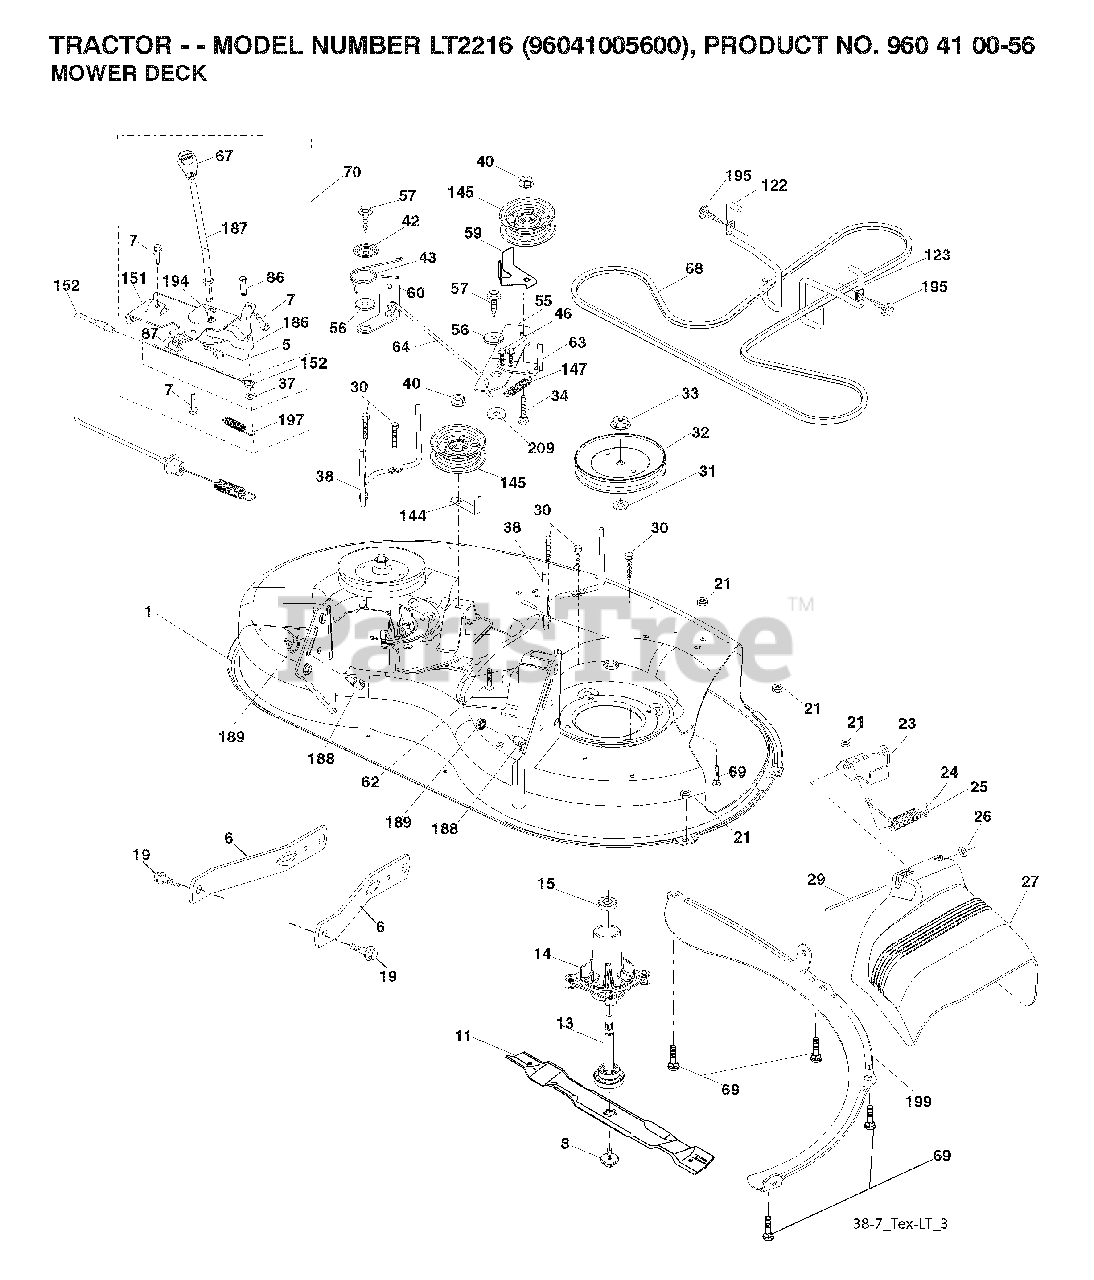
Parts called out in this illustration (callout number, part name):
5	RETAINER-SPRNG RB
6	ARM.SUSPENSION.MOWER.R
7	SCREW
8	BOLT.WASHER.ASM.7/16-2
11	BLADE 38" PREMIUM
13	SHAFT.ASM.MDRL.N/GREASE.38
14	HOUSING MANDREL
19	BOLT.SHOULDER
21	LOCKNUT
23	BRKT.DEFLECTOR.38"2005+
24	CAP-SLEEVE LT
25	SPRING.TORSION.DEFLECT
26	NUT PUSH M
29	ROD.HINGE
30	SCREW, WASHER HEAD
31	WASHER.SPACER.MANDREL
32	PULLEY.MANDREL.5.0.PD.38"
33	NUT.FLANGE.LOCK.TOP
34	BOLT.3/8-16X1.50
38	KEEPER BELT LH MANDREL
40	NUT LOCK FLG 3/8-16 UNC
42	SPRING.TORSION.BRAKE
43	SRPING.TORSION.RETAINE
46	SCREW.1/4-20X5/8
55	IDLER.ARM
56	SPACER.RETAINER
57	SCREW 3/8-16X1
59	GUARD, BELT
60	ARM BRAKE MOWER RH 38"
62	BOLT.3/8-16X1.50
63	ARM BRAKE MOWER RH
64	LINK BRAKE
67	HANDLE.CLUTCH.CABLE.LT
69	BOLT
70	CLUTCH.ASM.MANUAL.LT.TEX
86	PIN ATTACHMENT CABLE
87	SWITCH.INTRLCK.CLUTCH.
122	KEEPER BELT ENGINE LH
123	KEEPER BELT RH
144	KEEPER BELT
145	PULLEY.IDLER.48"PRIMARY
147	SPRING RETURN
151	BRACKET.CLUTCH CABLE.TEX
152	CLUTCH CABLE
186	ARM ACTUATOR
188	STUD.FASTNER.W/ANTI-ROTATE
189	NUT LOCK HEX FLANGE 5/16-18
194	BEARING.CONTROL.LEVER.CLUTCH
195	SCREW, 3/8-16X3/4
197	SPRING.PLUNGER.ACTUATOR
199	BAFFLE VORTEX
209	WASHER 12/32X2X10GA
